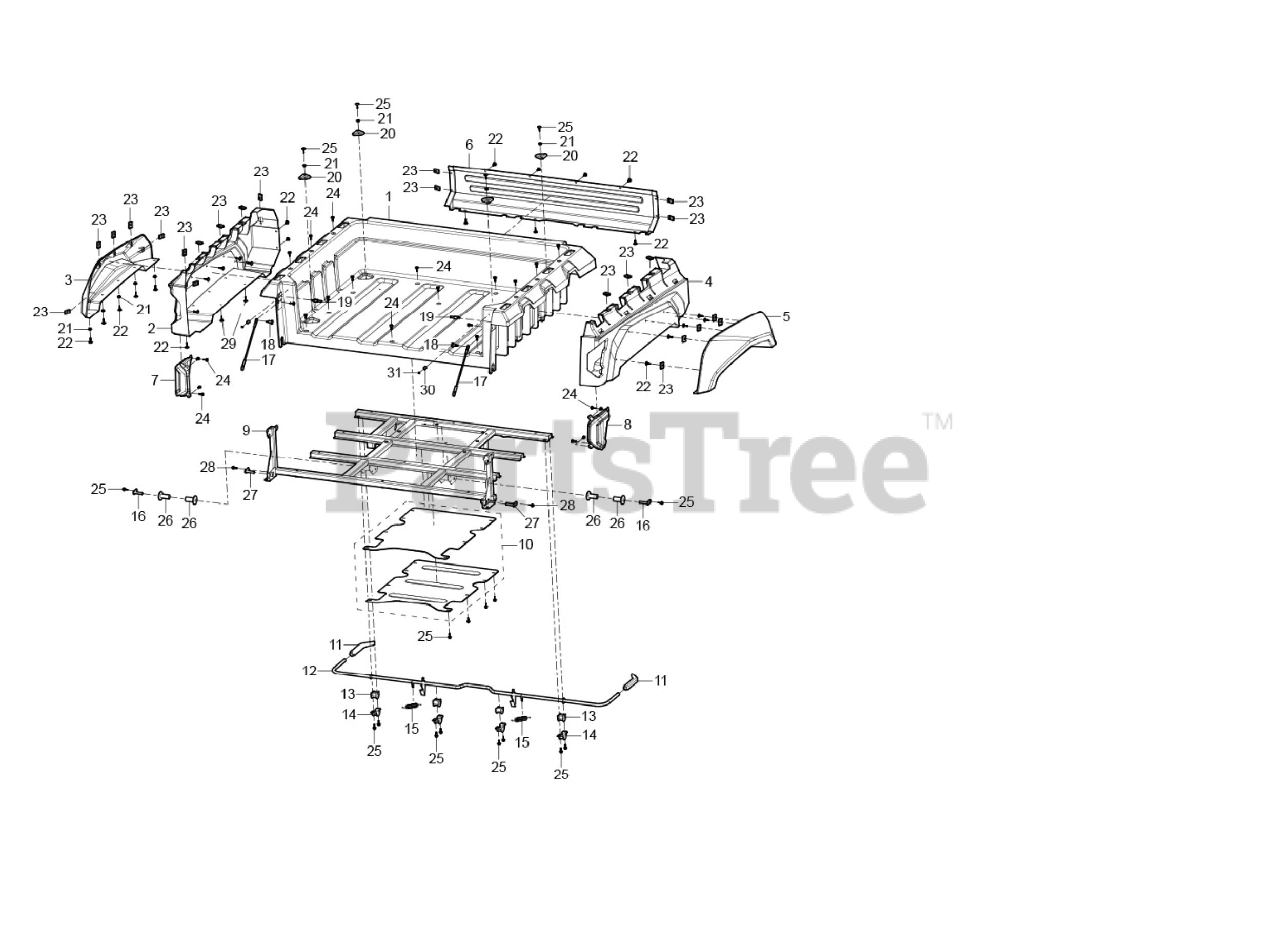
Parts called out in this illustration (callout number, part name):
1	CARGO BED
2	CARGO BED SIDE PANEL LEFT RED
2	CARGO BED SIDE PANEL LEFT YELLOW
2	CARGO BED SIDE PANEL LEFT BLUE
2	CARGO BED SIDE PANEL LEFT BLACK
2	CARGO BED SIDE PANEL LEFT CAMO
3	FENDER - REAR LEFT TOP
4	CARGO BED SIDE PANEL RIGHT RED
4	CARGO BED SIDE PANEL RIGHT YELLOW
4	CARGO BED SIDE PANEL RIGHT BLUE
4	CARGO BED SIDE PANEL RIGHT BLACK
4	CARGO BED SIDE PANEL RIGHT CAMO
5	FENDER - REAR RIGHT TOP
6	CARGO BED FRONT PANEL
7	TAIL BRAKE LIGHT ASSEMBLY - REAR LEFT
8	TAIL BRAKE LIGHT ASSEMBLY - REAR RIGHT
9	CARGO BED FRAME
10	HEAT PROTECTOR - CARGO BED
11	RELEASE LEVER GRIP
12	CARGO BED RELEASE LEVER KIT
13	RELEASE LEVER CUSHION
15	Tension Spring 2x 14x40
16	PIN - CARGO BED KIT
17	CABLE - CARGO BED DOOR J
18	BLOT HExAGON SOCKET SHOULDER M8x15-10x14.5
19	BLOT HExAGON SOCKET SHOULDER M8x15-10x10-53
20	HOOK - CARGO BED
21	HExAGON FLANGE HEAD NUT M6
22	Cross Large Plate Head Screw M6x16
23	CLAMP NUT M6x6
24	Socket Hex Flat Head Bolt M6x16
25	Hexagon Flange Bolt M6x16
26	BUSHING - PLASTIC 12x18
27	HINGE STRAP PLATED
28	BOLT HExAGON FLANGE HEAD M8x12
29	SCREW - CROSS HEAD SELF DRILLING ST4.8x16
30	CARGO DOOR SHOCK ABSORBER
31	SCREW CROSS HEAD SELF DRILLING ST4.2x13
